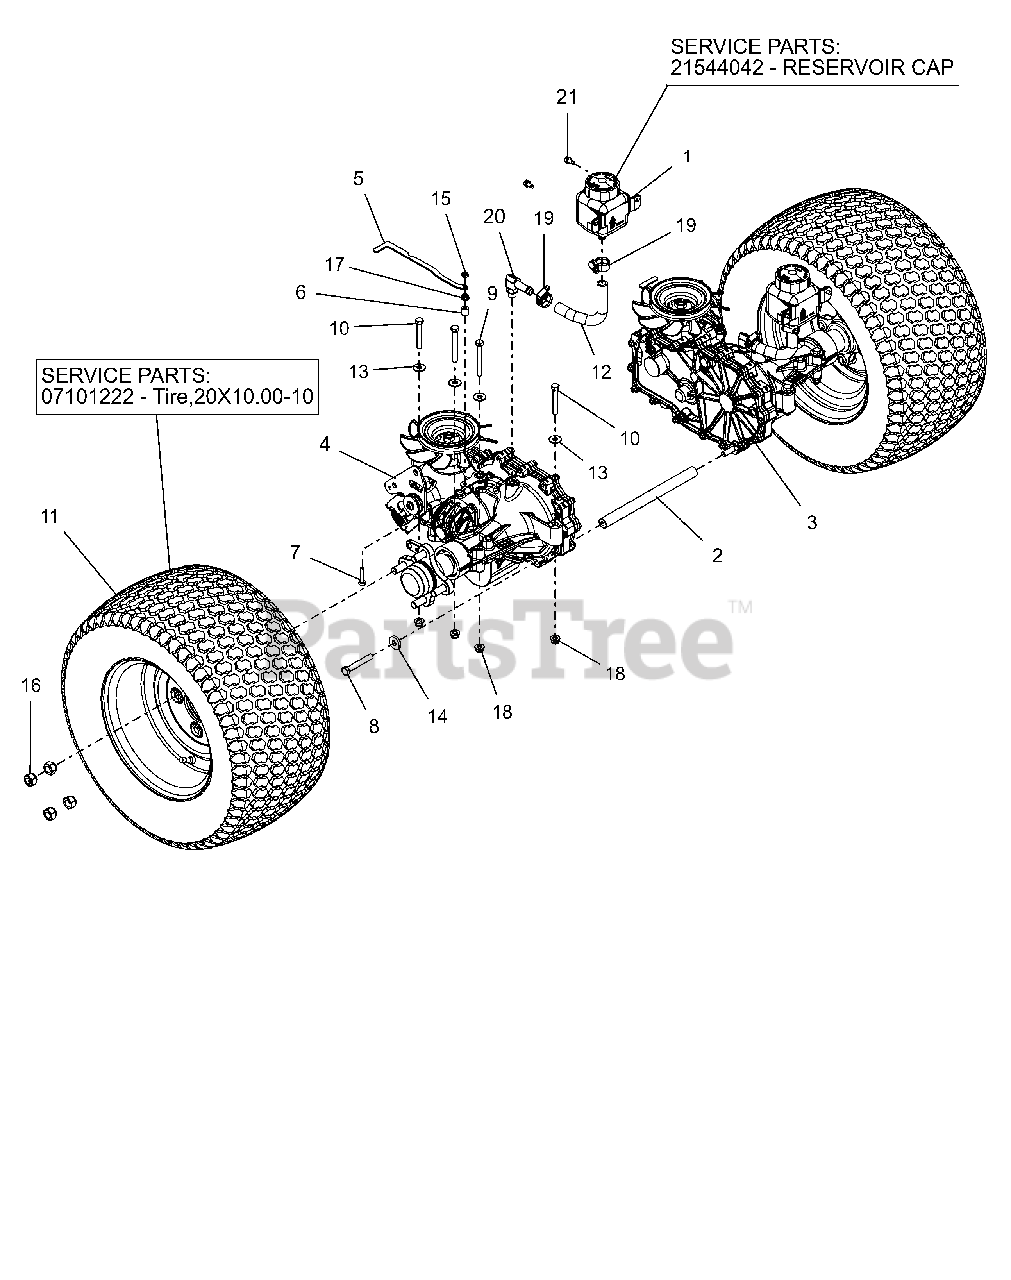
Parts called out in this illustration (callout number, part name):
1	TANK, EXPANSION
1	CAP, HYDRO RESERVOIR REPLAC.
2	ROD, TRANSAXLE BRACE 9.27
3	TRANSAXLE,ZT2800 LH
4	TRANSAXLE,ZT2800 RH
5	BRKT, DUMP VALVE
6	BSHG-SLV .265X.500X.500
7	@BLT-HEX .25-20X1.25 GR5 YWZC
8	@BLT-HEX .38-16X2.50 GR5 YWZC
9	@BLT-HEX .31-18X2.75 GR5 YWZC
10	@BLT-HEX .31-18X2.25 GR5 YWZC
11	ASM, WHL/TIRE 20X10.00-10
11	TIRE, 20X10.00-10 (OTR)
12	HOSE, FORMED LH XL
13	@WSHR-FL-STL.38X.875X.083 YWZC
14	WSHR-FL-STL .406X1.00X.188 YWZ
15	NUT-LK-CTR JAM .25-20 YWZC
16	WHEEL NUT .500-20 YZ
17	@NUT-SPNLK-FLG .25-20 YWZC
18	@NUT-LK-NYL-FLG .31-18 YWZC
19	CLAMP,.88 DIA. HOSE
20	FITTING, HYD (90 DEG)
21	SCR-TAP .25-20X.50 HWH TR YWZ
